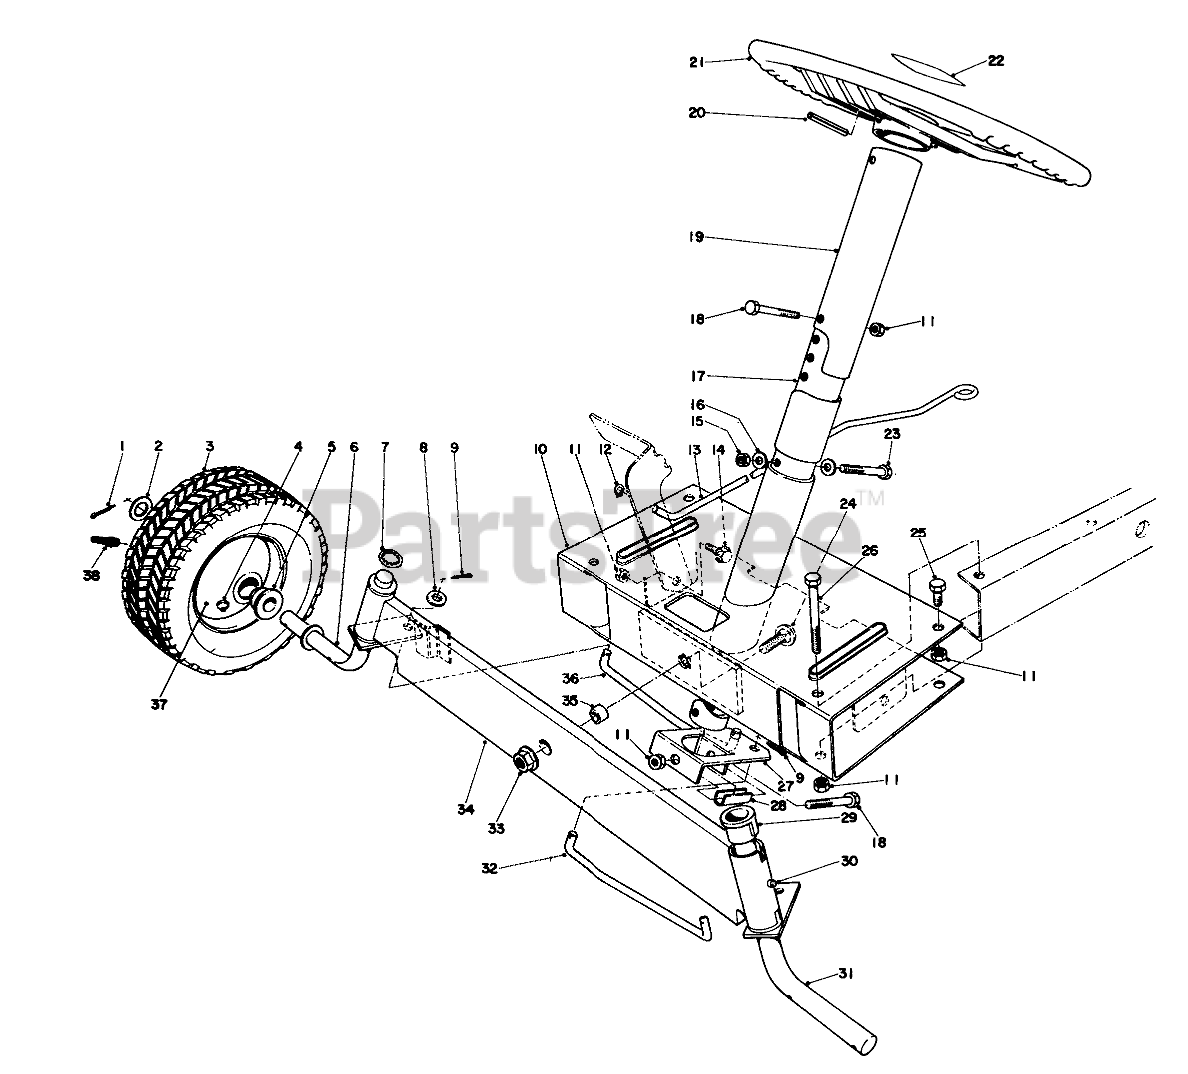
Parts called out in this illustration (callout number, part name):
1	PIN-COTTER
2	WASHER-FLAT
3	Tire Turf King
4	FITTING-GREASE
5	BUSHING
6	Spindle-R.H.
7	Retaining Ring
8	Washer
9	PIN-COTTER
10	Front Frame
11	NUT-LOCK, CONE
12	Retaining Ring
13	Brake Rod
14	SCREW-SHOULDER
15	NUT-LOCK, CONE
16	WASHER-FLAT
17	Steering Tube Inner
18	SCREW-HH
19	Steering Tube Outer
20	PIN-ROLL
21	Steering Wheel
22	Decal
23	SCREW-HH
24	SCREW-CARR
25	SCREW-HH
26	SCREW-HH
27	Steering Lever
28	Spacer-Steering Tube
29	BUSHING
30	GREASE FITTING
31	Spindle, L.H.
32	Tie Rod-L.H.
33	NUT-HF
34	Front Axle
35	FRONT AXLE SPACER
36	Tie Rod-R.H.
38	STEM-VALVE
